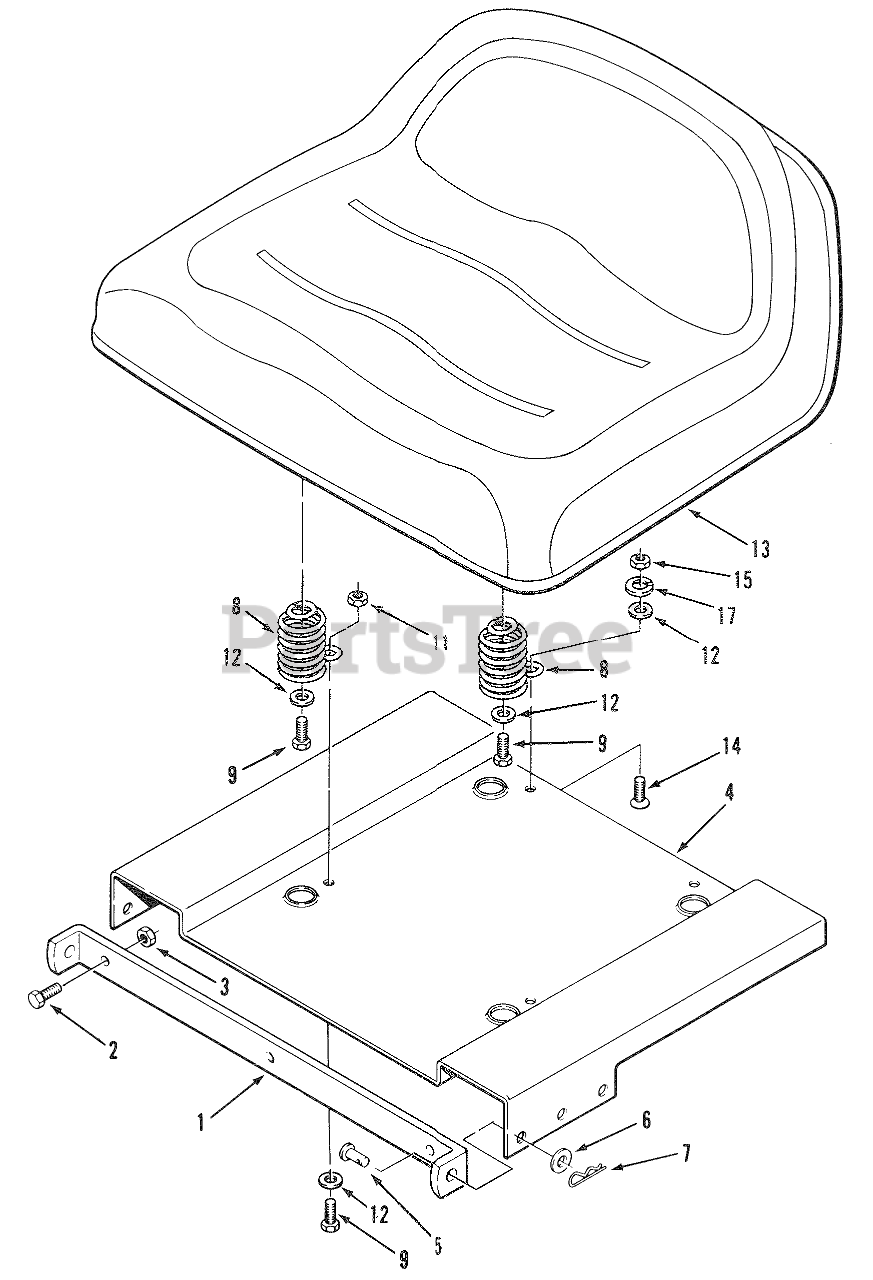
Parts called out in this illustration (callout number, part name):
1	BRACKET - SEAT MO R
2	Bolt
3	Nut
4	PLATE-SEAT PIVOT R
6	WASHER-SPRING
7	Hairpin
8	SPRING SEAT
9	Bolt
11	Nut
12	WASHER 5/16 SAE
13	SEAT V-550 LESS LOGO
14	Screw 5/16-18 X 3/4
15	Nut
17	Lockwasher
